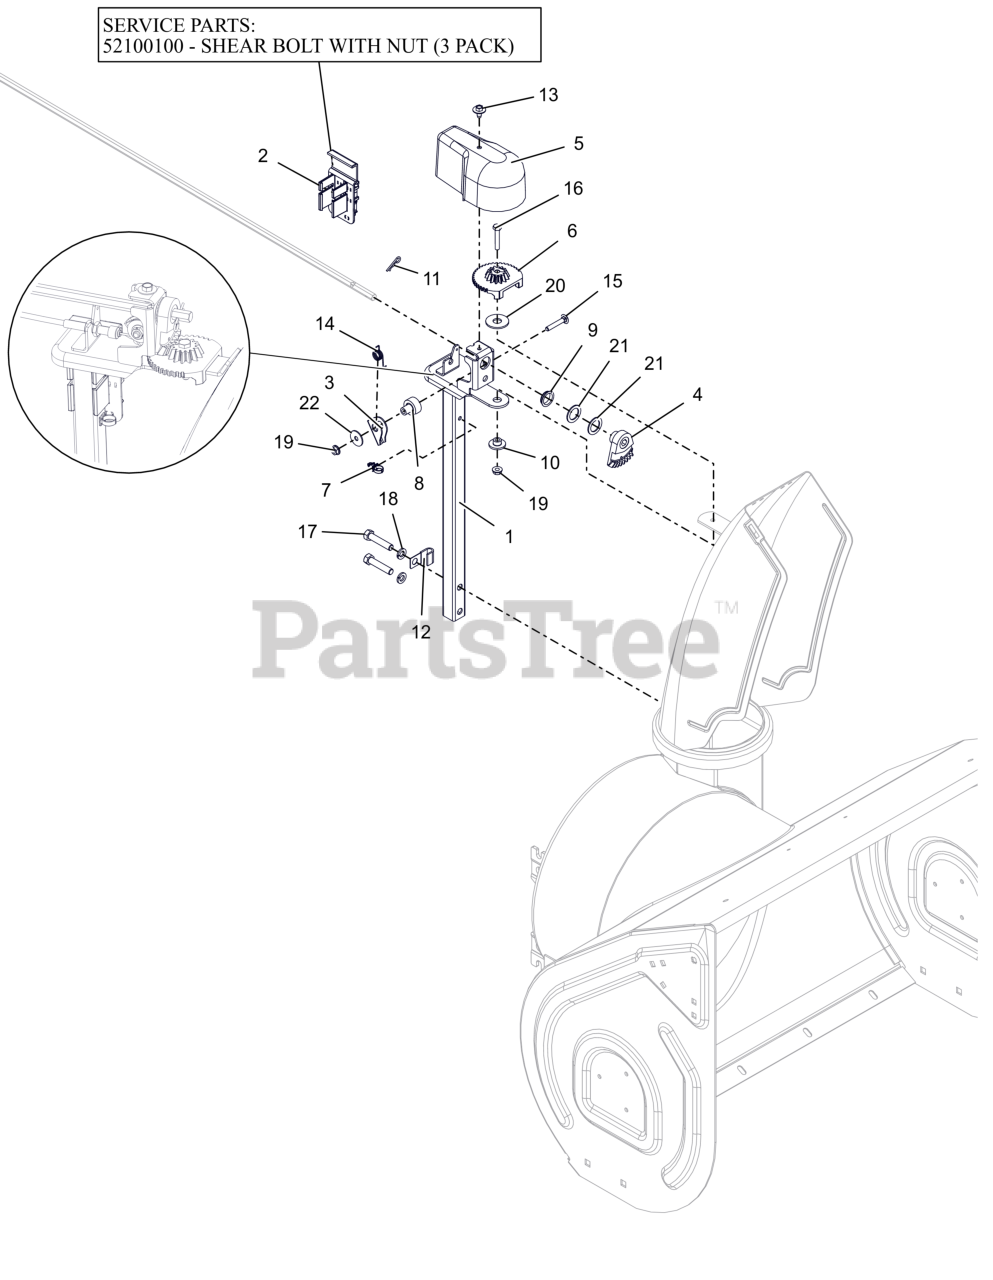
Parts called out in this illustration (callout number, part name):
1	PEDESTAL, CHUTE - QUICK STICK
2	HOLDER W LARGE SHEAR BOLT /NUT
2	SHEAR BOLT SERVICE ASSEMBLY
3	ARM, LOCKING
4	GEAR, CHUTE-ACTUATION
5	COVER, CHUTE GEAR
6	GEAR, CHUTE
7	CLIP, CABLE GUIDE
8	BUSHING, LOCK ARM
9	BUSHING, POLYLINER-.75 SNAPIN
10	BSHG-FLG .265X.477X.375X1.00
11	PIN, HAIR #213 .08X1.19 ZCC
12	J-CLAMP
13	SCR, TAP .25-20X.50 LG HWH ZCC
14	SG-TORS
15	BLT, RHSN .25-20X1.50 G5 ZCC
16	BLT, HEX .25-20X1.50 G5 ZCC
17	BLT, HEX .38-16X1.75 G5 ZCC
18	WSHR,LK-REG .375X.094 ZCC
19	NUT-LK-CTR-FLG .25-20 ZC120
20	WSHR-FLT-NYL .515X1.375X.093
21	WSHR, FLT .754X1.125X.062 ZCC
22	WSHR,FLT .281X1.000X.063 ZCC
